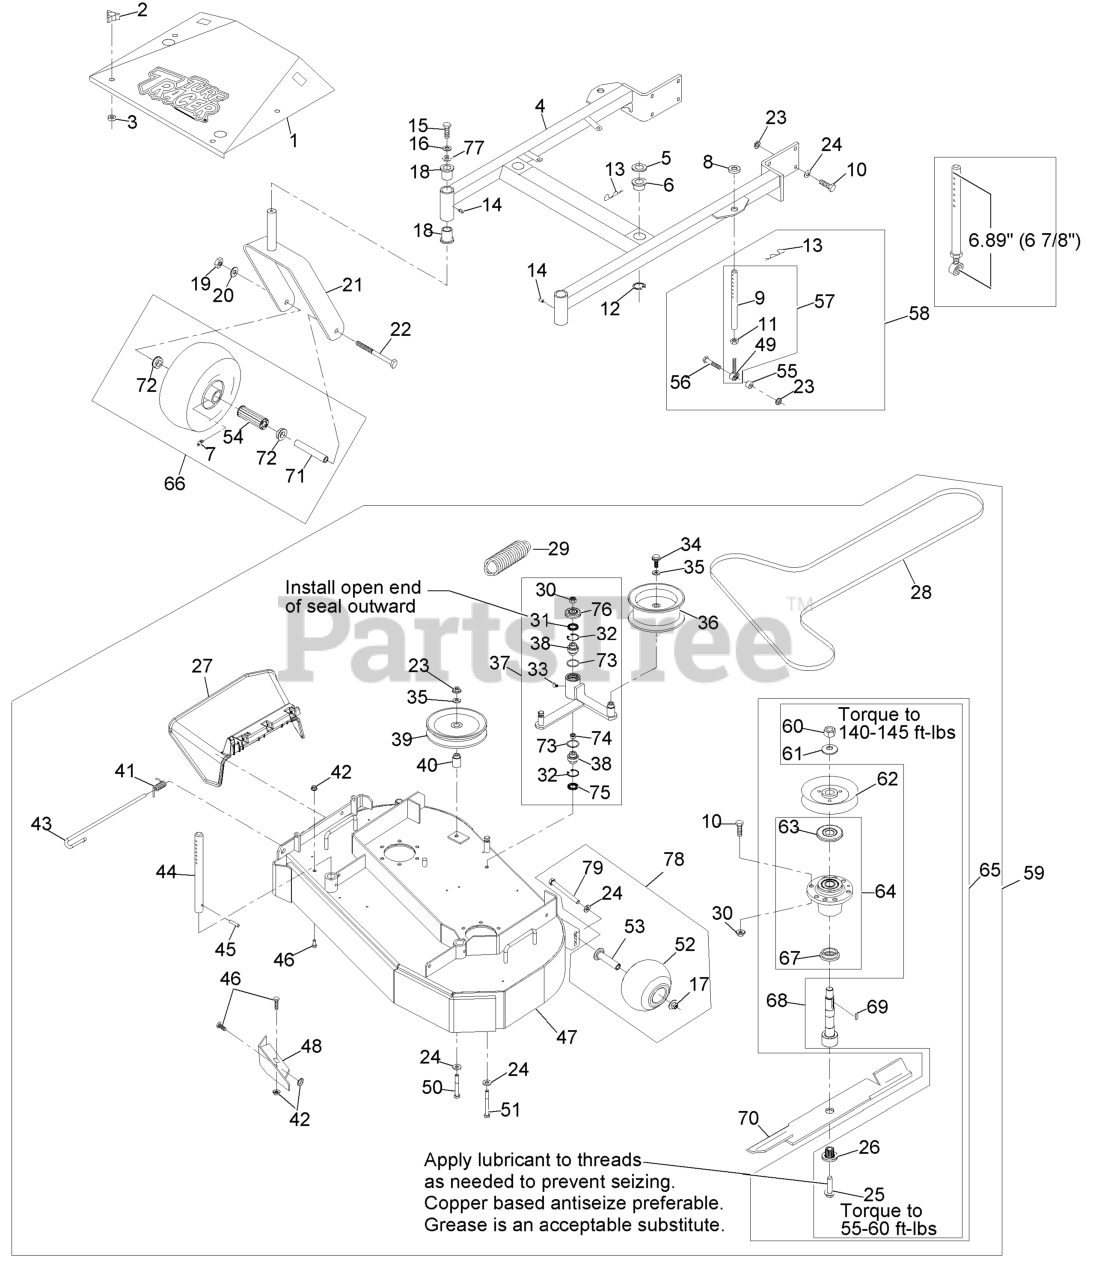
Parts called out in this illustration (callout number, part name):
1	ASM,SHIELD W/DECALS 36 TT
2	KNOB-3 PRONG
4	DECK SUPPORT W/BSHGS 36"
5	SPACER-DECK SUPPORT
6	BUSHING-DECK
7	FITTING-GREASE
9	LINK,SUPPORT
10	SCREW-HH
11	NUT-HJ
12	RING-RETAINING
13	PIN,HAIR COTTER
14	FITTING-GREASE
15	SCREW-HH
16	WASHER-LOCK
17	Nut-Nyloc 3/8-16 Flg
18	BEARING-FLANGED
19	NUT-HH
20	WASHER-LOCK
22	SCREW-HH
23	NUT-HHF, WHIZ
24	WASHER-BELLEVILLE
25	SCREW,SEMS 1/2-20 X 2.19
26	BUSHING,SPLINED
27	CHUTE DEFLECTOR XRK M056
28	BELT,DECK DRIVE
30	NUT-LOCK, NI
31	SEAL-LIP, SINGLE
32	RING-SNAP
33	FITTING-GREASE, 90 DEG
34	SCREW-HHF
35	WASHER-FLAT
36	IDLER-PULLEY, FLAT
37	KIT, DECK IDLER TTHP 36"(
38	BEARING-SPHERICAL
39	PULLEY-IDLER
40	BUSHING-IDLER
41	SPRING, TORSION
43	PIN-CHUTE
44	ROD,DECK SUPPORT
46	SCREW-HH
47	ASM,DECK W/DECALS TTHP/MH
48	BAFFLE,DOGLEG
49	BALLJOINT
50	SCREW-HH
51	SCREW-HH
52	ROLLER-SCALP, ANTI
53	AXLE, ROLLER
54	BEARING
56	SCREW-HH
58	KIT,SUPPORT LINK W/PIN
59	Assembly, Cutting Deck Complete
62	SHEAVE,W/HUB 5.72
63	GUARD-BEARING, TOP
64	KIT, CUTTER HOUSING
65	ASM, CUTTER HSG
66	KIT, SP CASTER WHEEL REPL
67	SPACER-GUARD, BOTTOM
68	KIT, SPLINED SPINDLE 103-
69	KEY-RECTANGLE
72	BUSHING
75	SEAL-LIP, DOUBLE
76	GUARD-TOP
78	KIT, ANTI-SCALP ROLLER
79	SCREW-HH 3/8-16 X 3 3/4 GR 8
